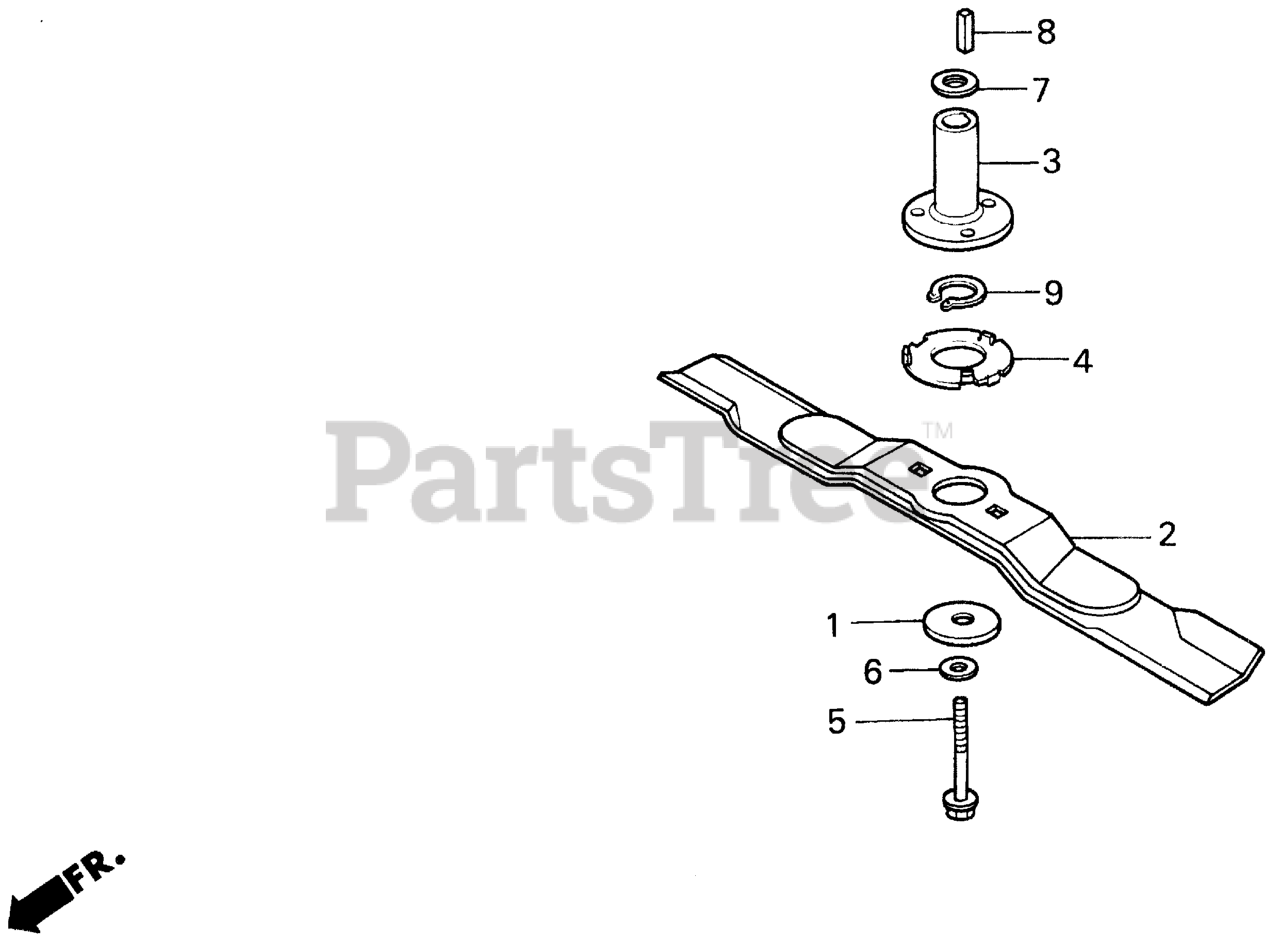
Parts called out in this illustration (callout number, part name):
1	WASHER (42X8.5)
2	BLADE, ROTARY
3	HOLDER, BLADE
4	WASHER, BLADE HOLDER
5	BOLT, UBS (8X50)
6	WASHER, SPECIAL (22X8.5X2)
7	WASHER, THRUST
9	CIRCLIP (INNER) (17MM)
